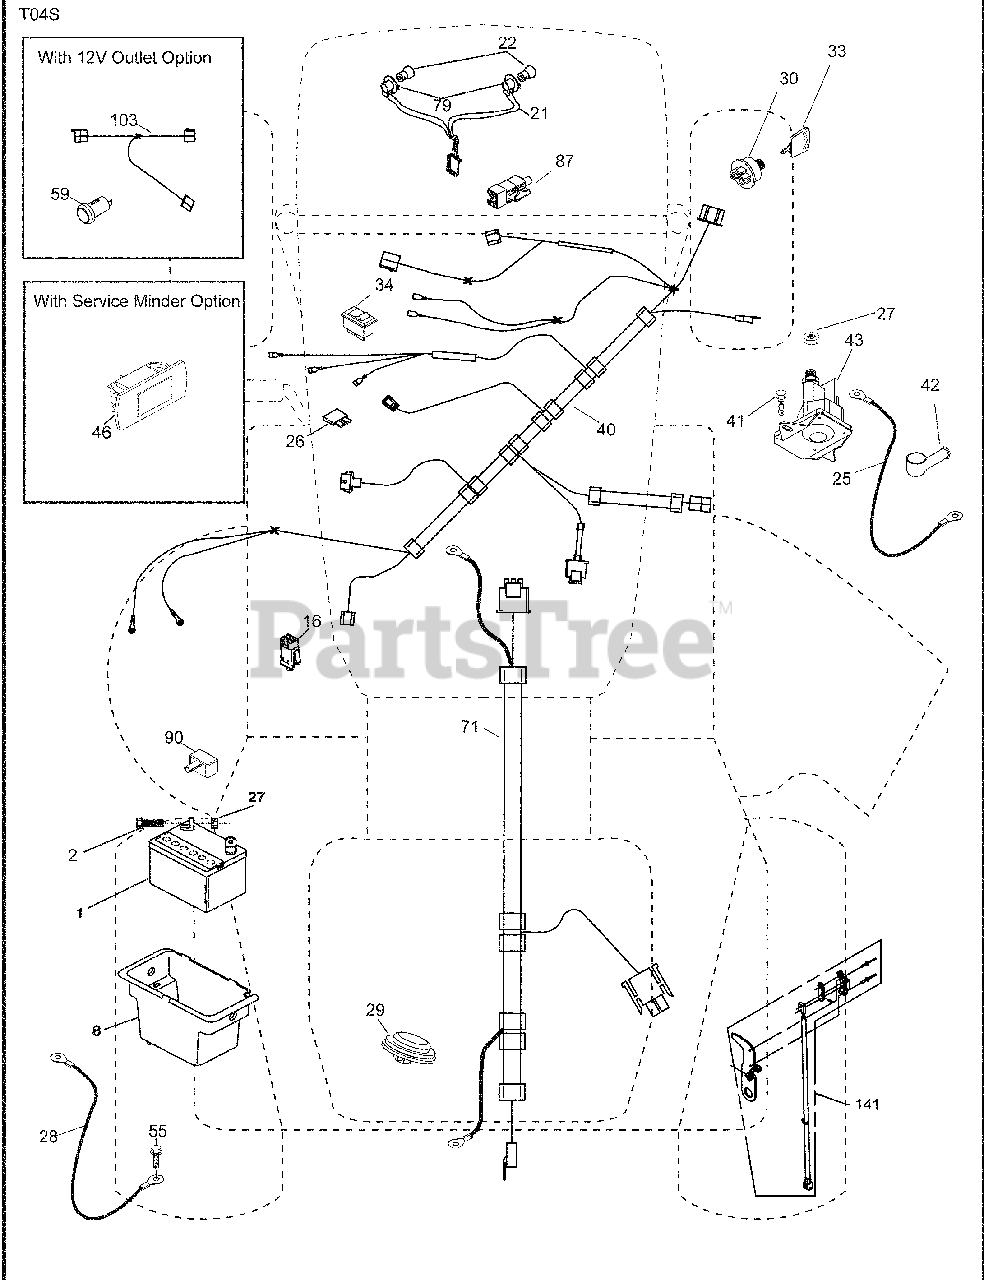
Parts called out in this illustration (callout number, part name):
1	Battery
2	Bolt Hex Head 1/4-20 x 3/4
8	Box Battery
16	Switch Interlock Push-In
21	Harness Socket Light w/4152J
22	Bulb Light
25	Cable Starter
27	Nut Keps Hex 1/4-20 unc
28	Cable, Ground
29	Switch, Seat
30	Switch, Ign
34	Switch Light/Reset
40	Harness Ign.
41	Screw Thd Cut 1/4-20 x 1/2
42	Cover, Terminal
43	Solenoid
46	Gauge Serviceminder Hrmtr
55	Screw Thdrol 5/16-18 x 3/4 TYTT
71	Harness Ign. Dash
79	Socket Asm. Bulb
87	Switch Interlock Clutch
90	Cover Terminal
141	Kit T2 ROS (71677)
